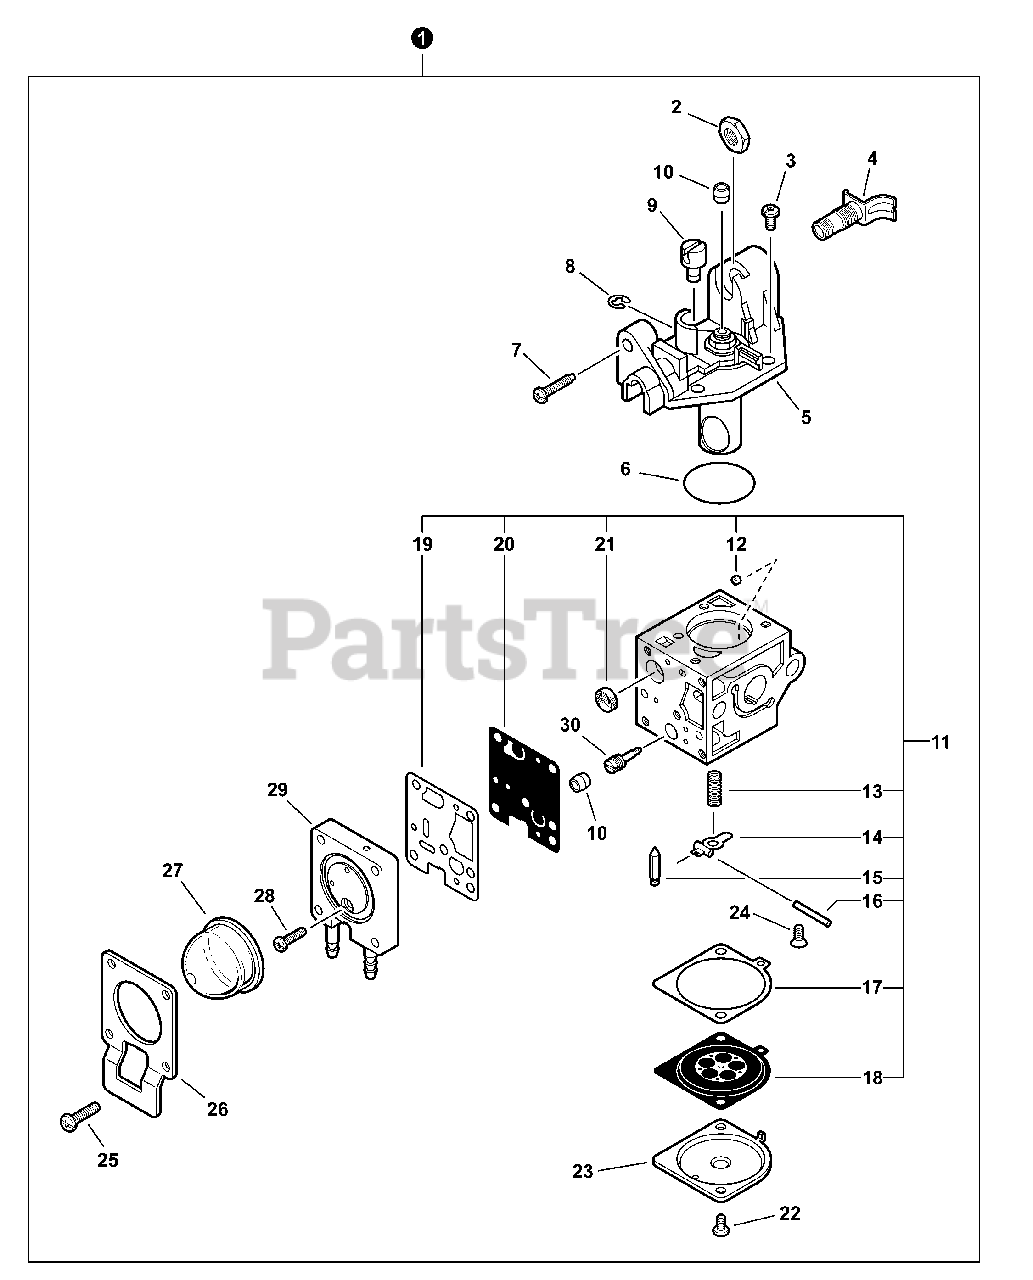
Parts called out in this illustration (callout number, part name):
1	CARBURETOR -- RB-K106
4	ADJUSTER, CABLE
5	ROTOR COVER ASSY
7	SCREW, IDLE ADJUST
8	RING, RETAINING
11	REPAIR KIT
12	GUIDE, ROLLER
13	SPRING, METERING LEVER
14	LEVER, METERING
15	VALVE, INLET NEEDLE
16	PIN, METERING LEVER
17	GASKET, DIAPHRAGM
18	DIAPHRAGM, METERING
19	GASKET, PUMP
20	DIAPHRAGM, PUMP
21	STRAINER
23	COVER, METERING
24	SCREW, METERING LEVER PIN
25	SCREW, PURGE BULB RETAINER
26	RETAINER, PURGE BULB
27	BULB, PURGE
28	SCREW, PURGE BASE
29	BASE, PURGE
30	NEEDLE - HIGH SPEED
